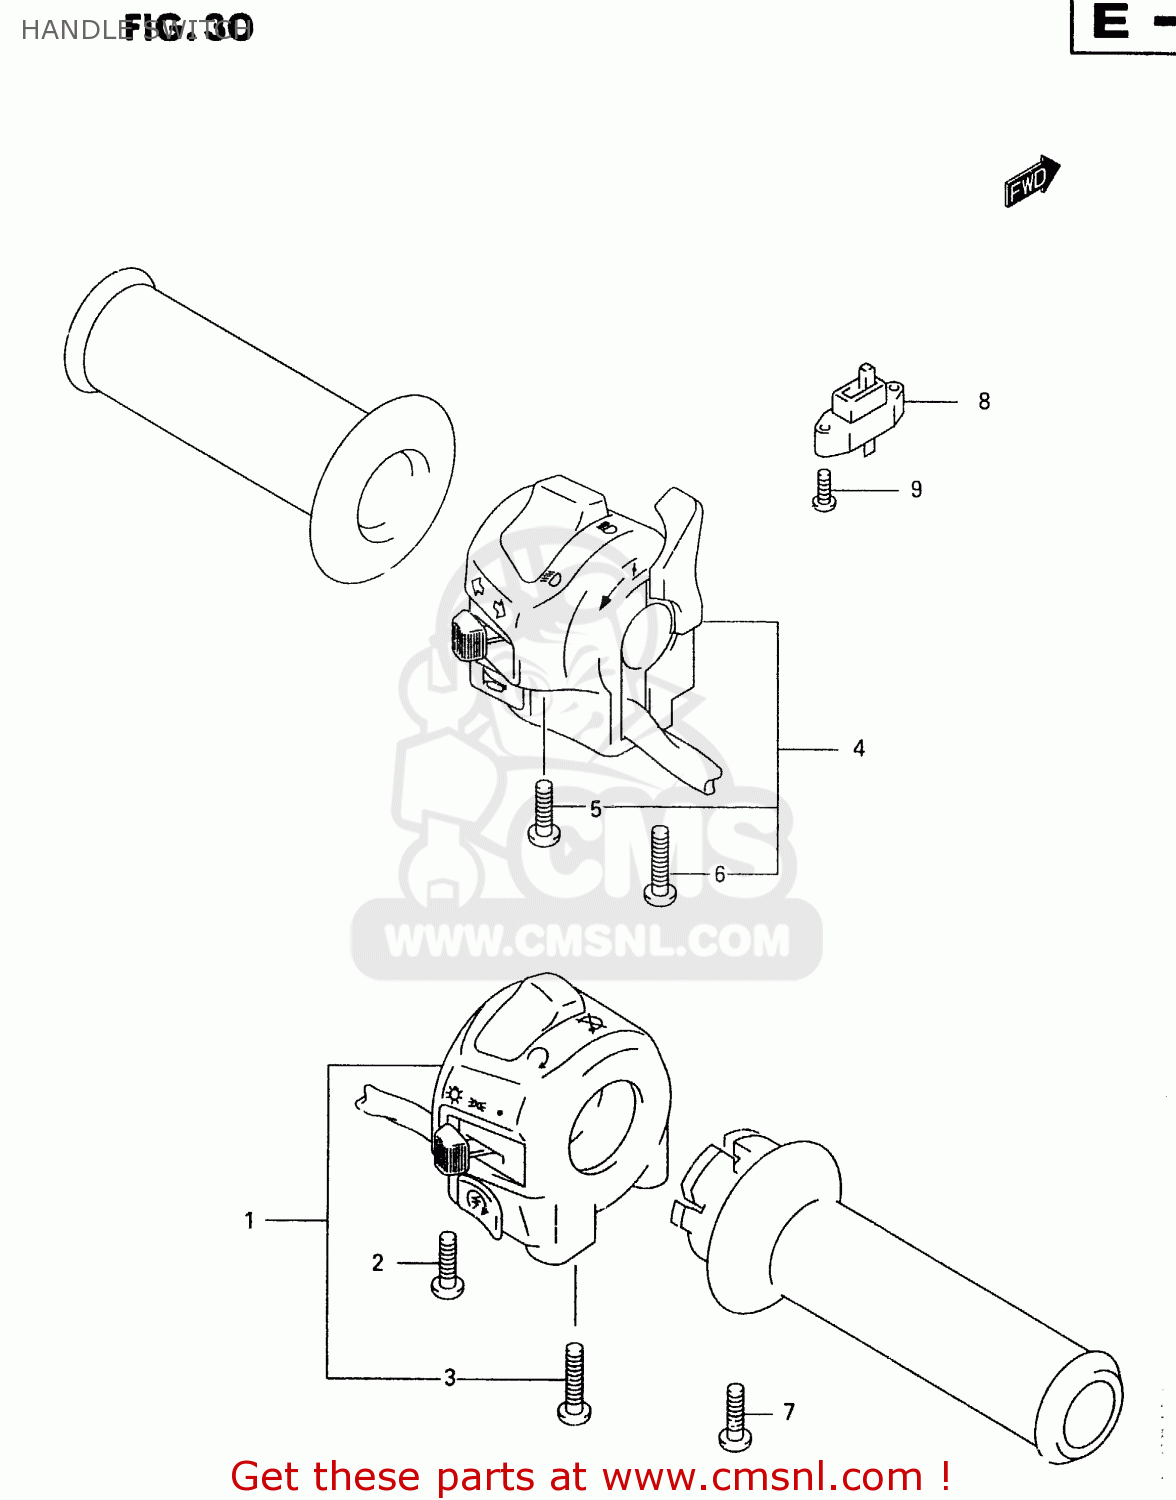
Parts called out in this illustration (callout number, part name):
1	SWITCH,HANDLE,
2	SCREW
3	SCREW
4	SWITCH,HANDLE,
5	SCREW
6	SCREW
7	SCREW
8	SWITCH ASSY,CLUTCH
9	SCREW
